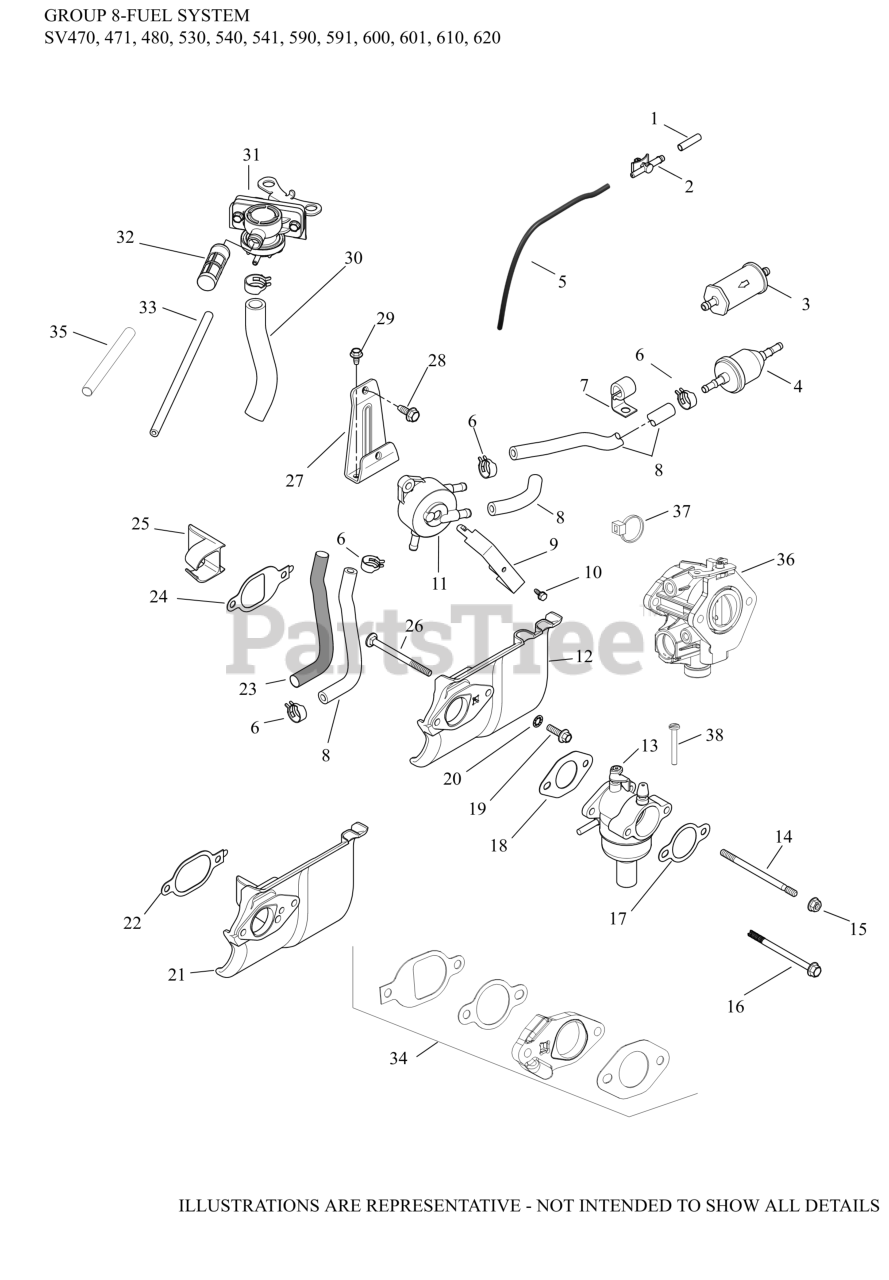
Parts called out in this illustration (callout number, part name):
4	FILTER,FUEL 51 MICRON (FUEL PUMP)
6	SPRING CLAMP, HOSE
7	CLIP, CABLE
8	HOSE,LW PERM.FUEL 24.00"-USE 25 111 81-S
11	PUMP, FUEL
12	KIT, HEAT DEFLECTOR
13	KIT,CARB (NIKKI) -USE 20 853 94-S
14	STUD, CARBURETOR
15	NUT, FLG M6X1.0
18	GASKET, CARBURETOR
19	SCREW, FLG M6x1.0x20
20	WASHER, INT TOOTH LOCK 1/4"
24	GASKET, HEAT DEFLECTOR
29	SCREW, FLG THD FRM M5X.8X10
NI	KIT, REPAIR CARBURETOR
NI	KIT, REPAIR GASKET
NI	KIT, HIGH ALTITUDE (4,000 - 8,000 FT.)
NI	KIT, SOLENOID AND LEAD
NI	KIT, CHOKE REPAIR
